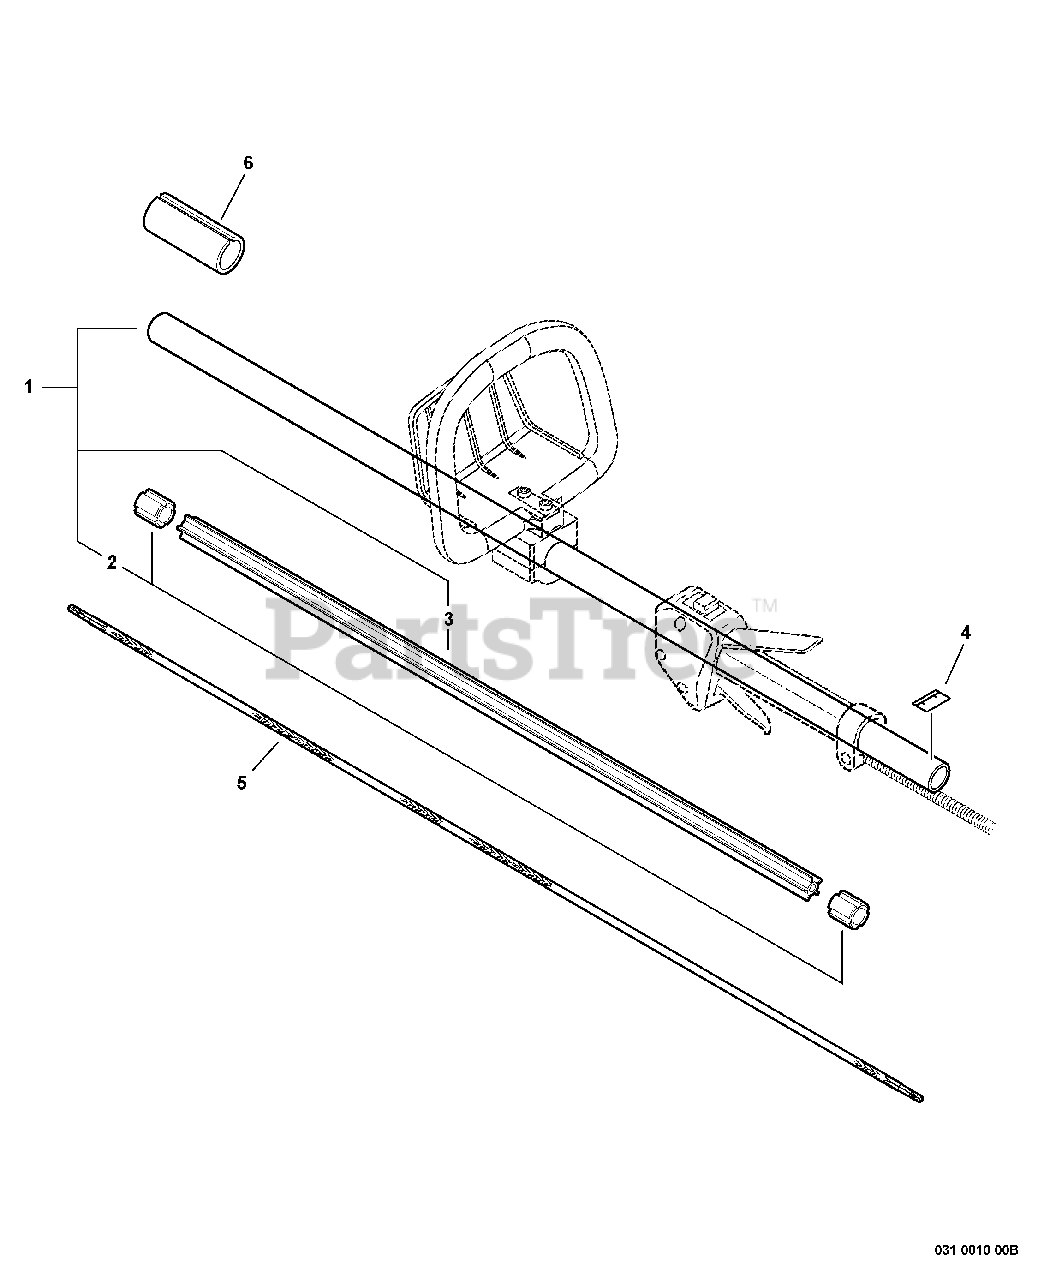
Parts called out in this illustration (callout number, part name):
1	MAIN PIPE ASSY
3	LINER - FLEXIBLE
4	LABEL - ALIGNMENT
5	DRIVESHAFT - FLEXIBLE
